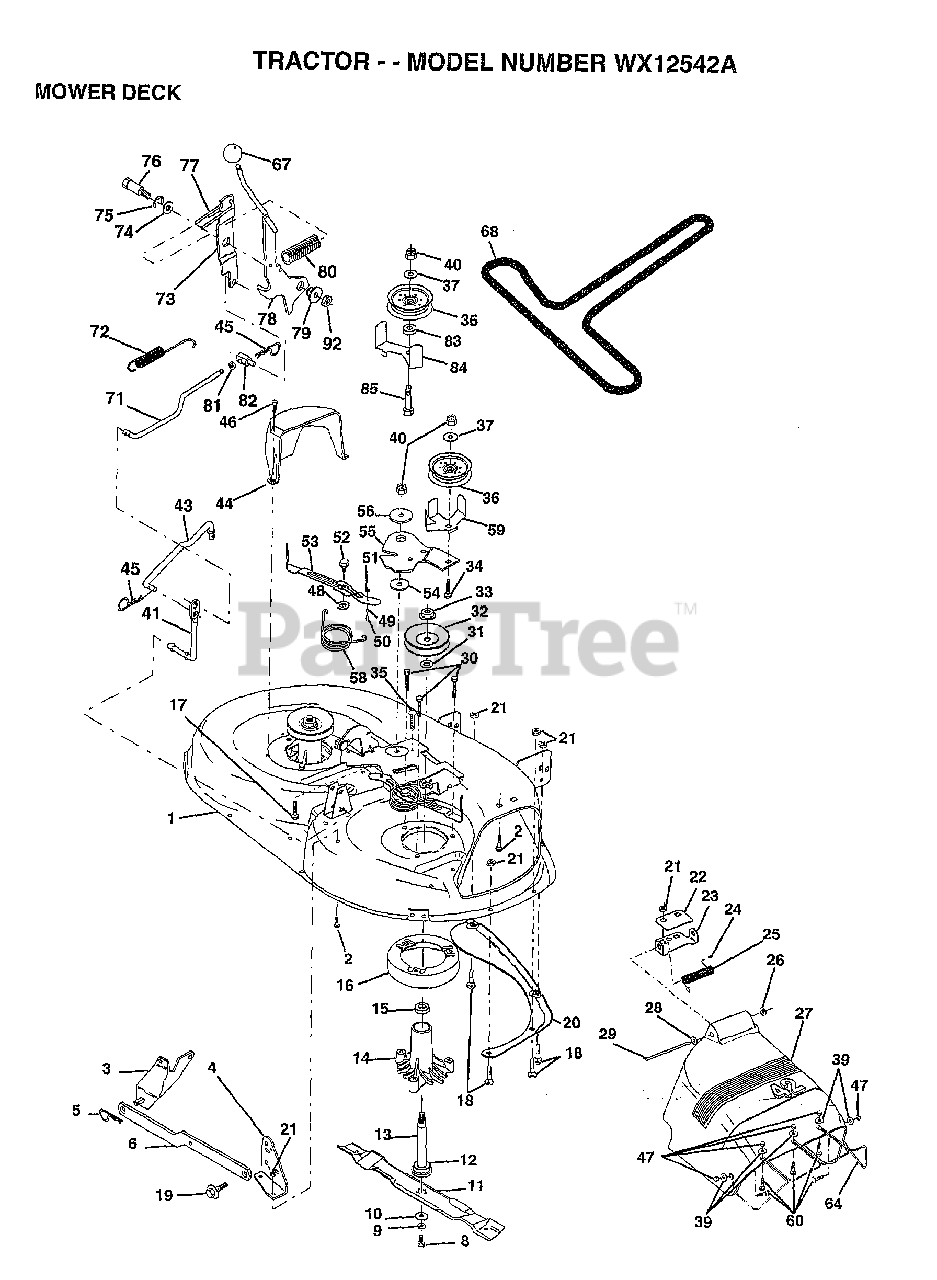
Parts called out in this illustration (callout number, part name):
1	DECK.WELD.42.
2	BOLT
3	BRKT ASM SWAY BAR
4	BRKT DECK SW BAR
8	BLADE BOLT
10	WASHER.HARD.BLADE
11	"BLADE.42"" HIPERF"
12	BEARING.BALL
14	HSG ASM MANDREL
15	BEARING
16	STRIPPER RND MWR
17	BOLT RDHD 3/8-16
18	BOLT
19	BOLT SHD 5/16-18
22	STIFFENER BRKT
23	DEFLECTOR BRKT
24	CAP-SLEEVE LT
26	NUT PUSH M
27	DEFLECTOR.CLIP.TU
28	WASHER
29	HINGE ROD
31	WASHER
34	BOLT
35	XMAS TREE FASTNER
36	FLAT IDLER PULLEY
37	WASHER
41	PIVOT ROD
43	ROD CLUTCH W/NIBS
44	GUARD MAND LH BLK
45	RETAINER M
46	SCREW.1/4-20X5/8
47	ACORN NUT RB
48	HARD SMALL WASHER
50	SHOULDER BOLT
51	LOCKNUT
52	BOLT.SHLD.5/16-18
53	BRAKE PAD ARM ASM
54	HARDENED WASHER
56	SPACER RETAINER
58	SPRING TORSN BRAK
59	GUARD IDLER TUV
60	SCREW
64	GUARD.FOOTREST.42
67	KNOB T(3/8 HOLE)
68	BELT.V.T-PATH
71	ROD CLUTCH 38/42
72	RETURN SPRING
73	CLUTCH ARM SECOND
74	WASHER
75	RING
76	SHOULDER BOLT
77	SPRING KEEPER
79	BUSHING
81	NUT
82	TRUNION ADJ
83	WASHER
85	BOLT RDHD 3/8-16
92	NUT
